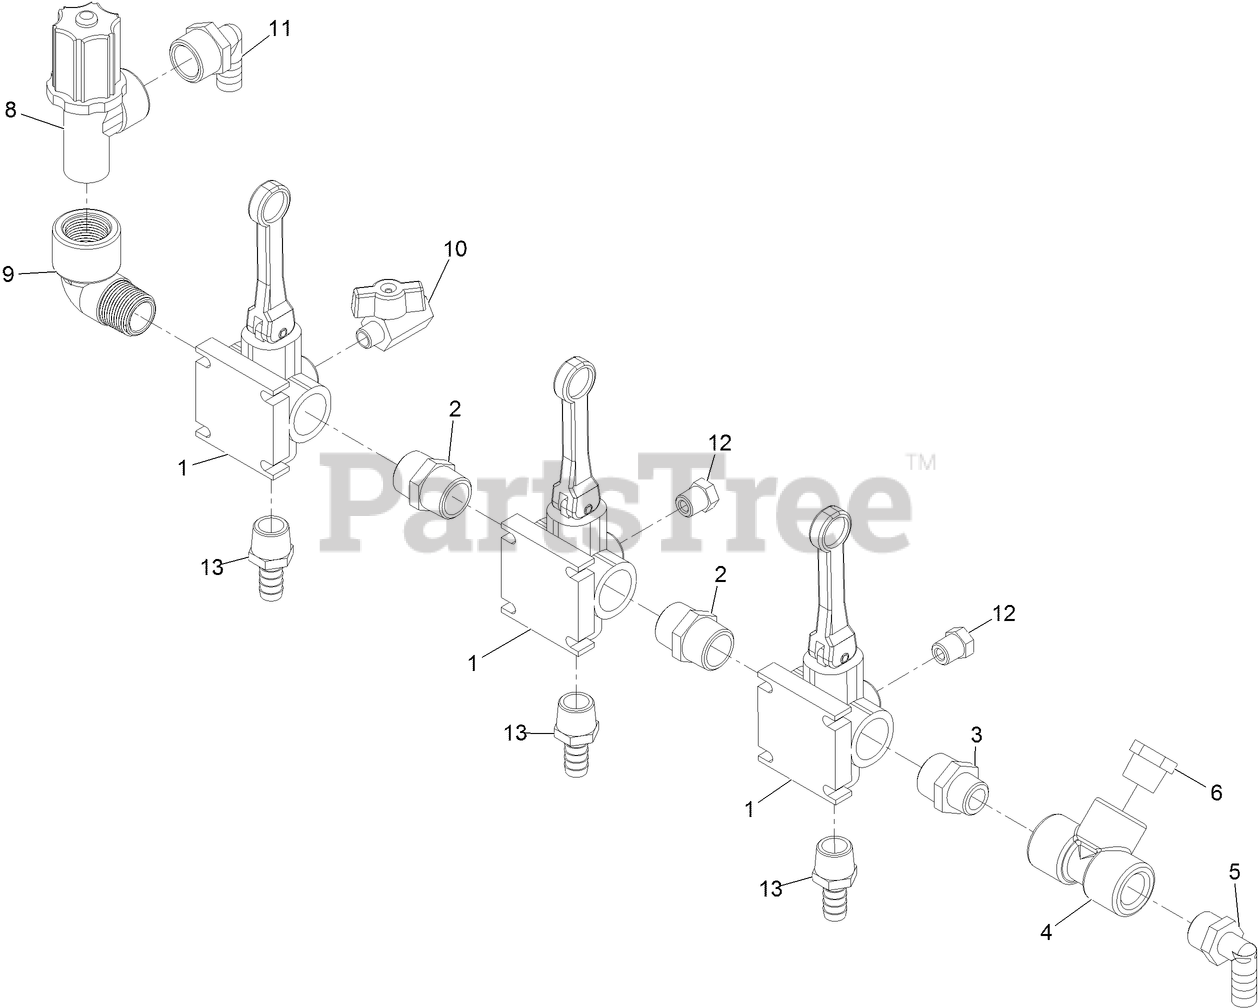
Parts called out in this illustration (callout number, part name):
1	VALVE-DIRECTO
2	FITTING-NIPPLE
3	FITTING-NIPPLE
5	FITTING-ELBOW, HOSEBARB
6	FITTING-REDUCER
8	VALVE-THROTTLE
9	ELBOW-90 DEG
10	VALVE-CHROME, 1/4
11	FITTING-ELBOW, 90
12	PLUG-VALVE
13	FITTING-HOSEBARB
